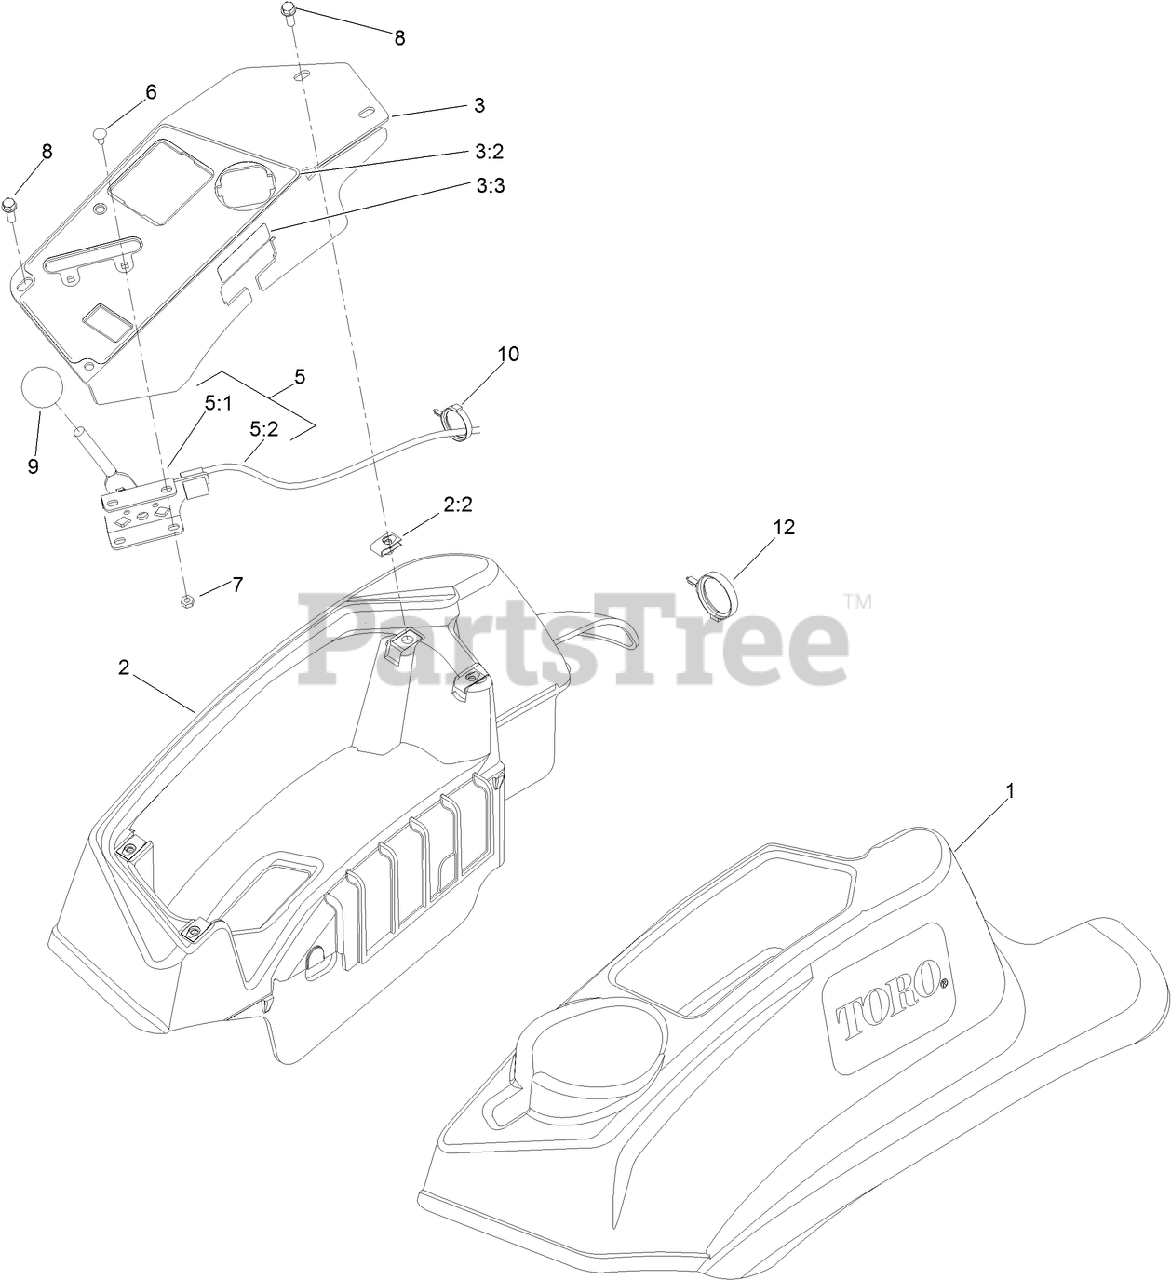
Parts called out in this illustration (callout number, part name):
1	CONSOLE-LH
2	RH CONSOLE ASM
3	CONTROL PANEL W/DECAL ASM
3:2	DECAL-PANEL, CONTROL
3:3	DECAL-FUSES
5	THROTTLE CONTROL ASM
5:1	LEVER-THROTTLE
5:2	CABLE-THROTTLE
6	BOLT-CARR
7	NUT-LOCK, NI
8	SCREW-HWH
9	KNOB-BALL
10	CLAMP-HOSE
12	CLAMP-HARNESS
